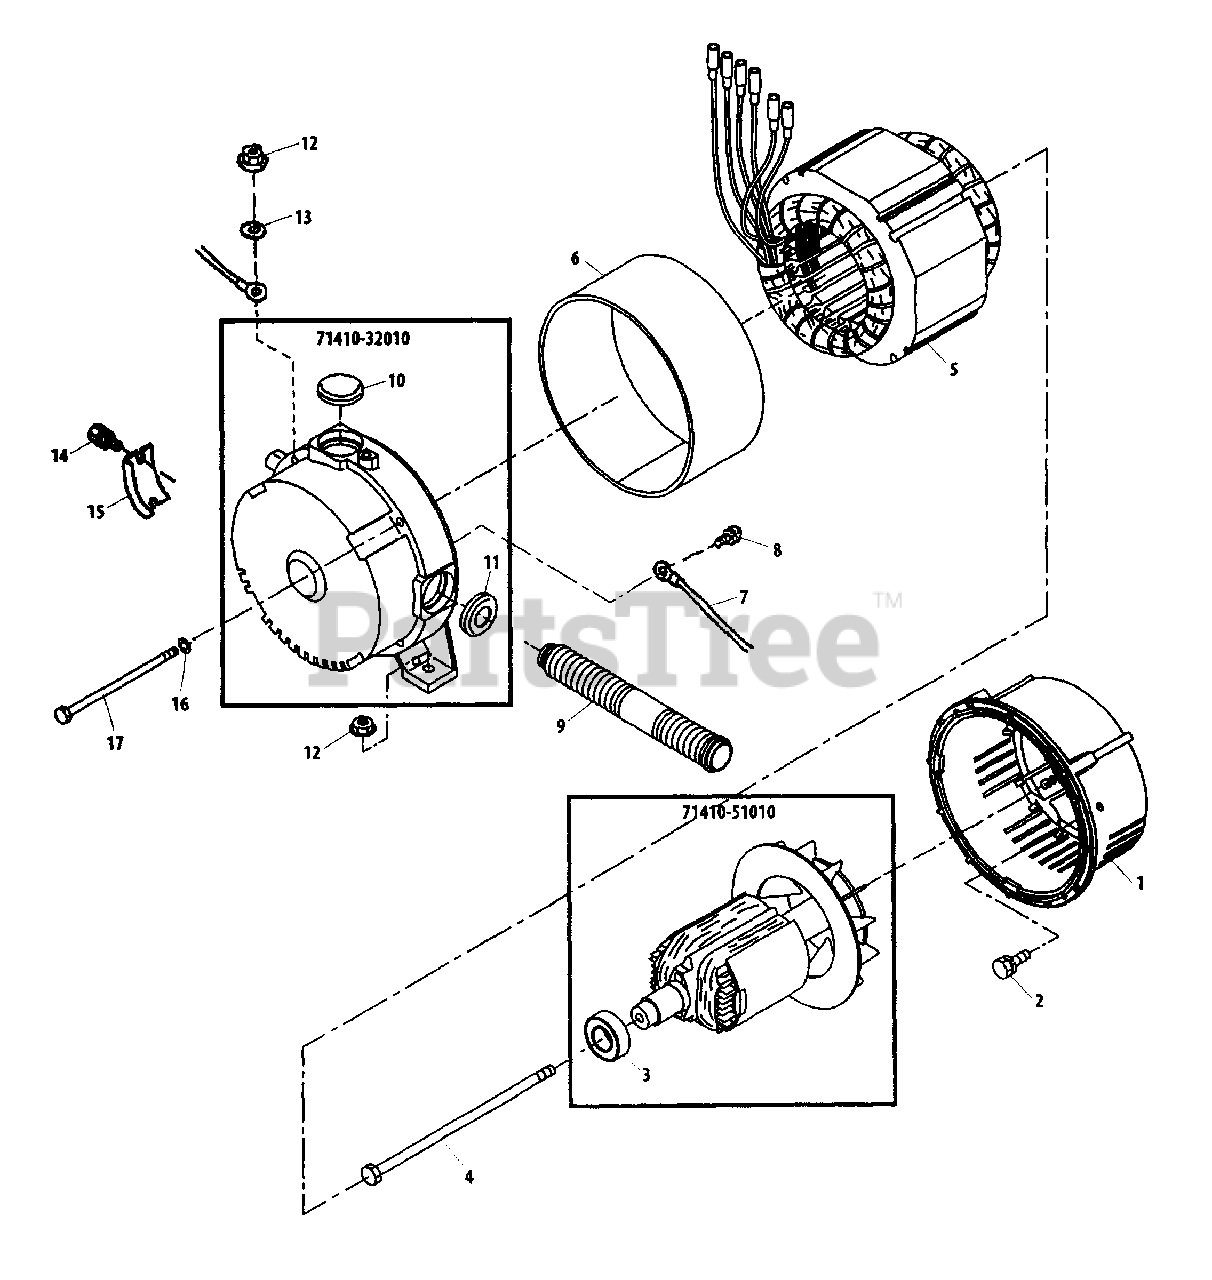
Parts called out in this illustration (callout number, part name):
1	FRONT COVER
3	BEARING, BALL
6	STATOR COVER
9	FLEXIBLE TUBE
12	NUT - FLANGE
13	WASHER
14	BOLT
15	BRUSH COVER
16	WASHER, SPRING 8
71410-32010	REAR COVER ASSY
71410-51010	ROTOR ASSY
